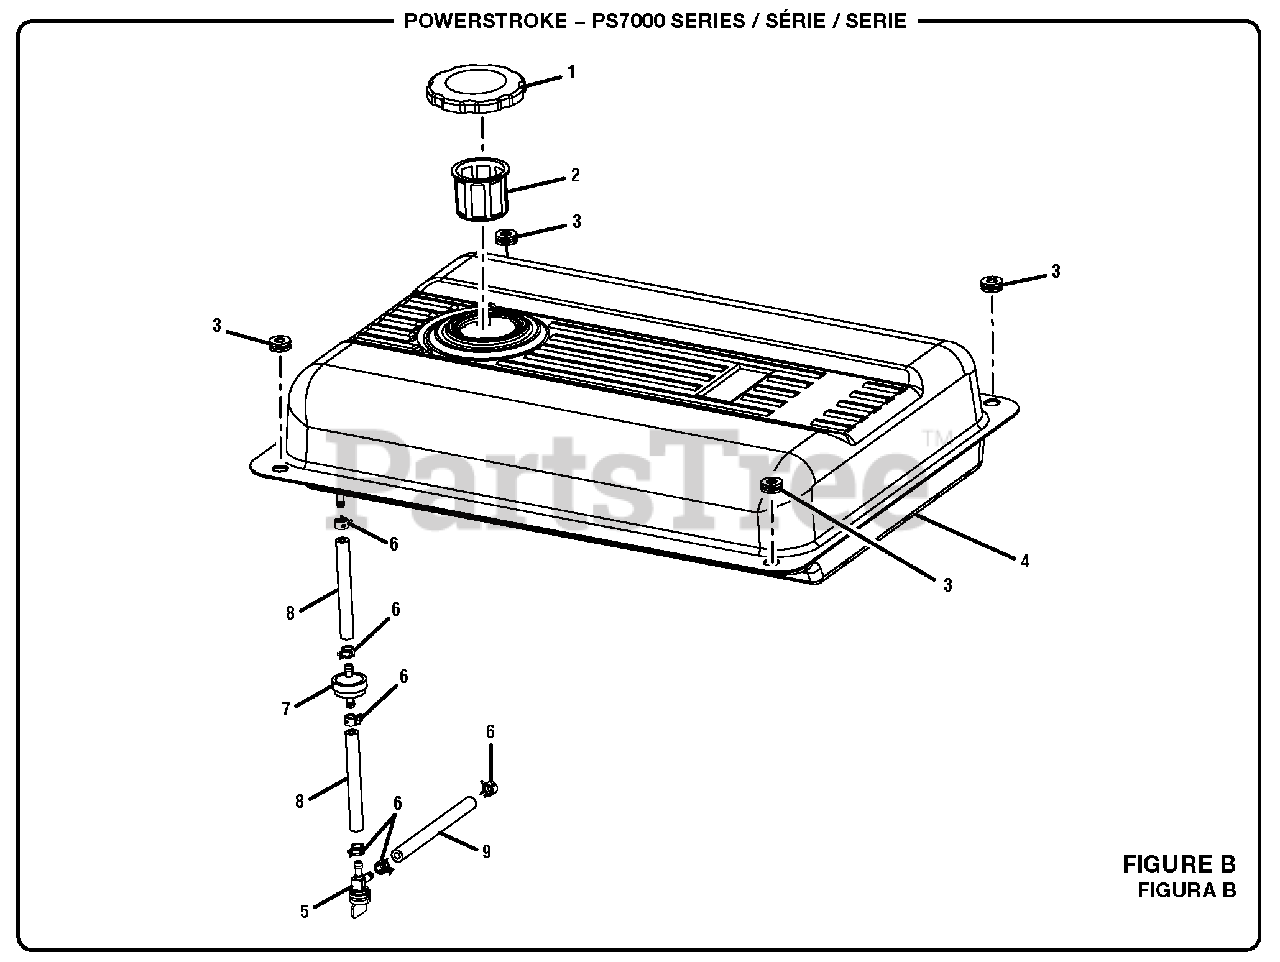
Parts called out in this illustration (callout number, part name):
1	Fuel Tank Cap
2	Fuel Tank Screen
3	Bushing w/Insert
4	Fuel Tank
5	Fuel Valve
6	Fuel Line Clamp (1/2 in.)
7	Fuel Line Filter
8	Fuel Line (1/4 in.)
9	Fuel Hose (1/4 in.)
